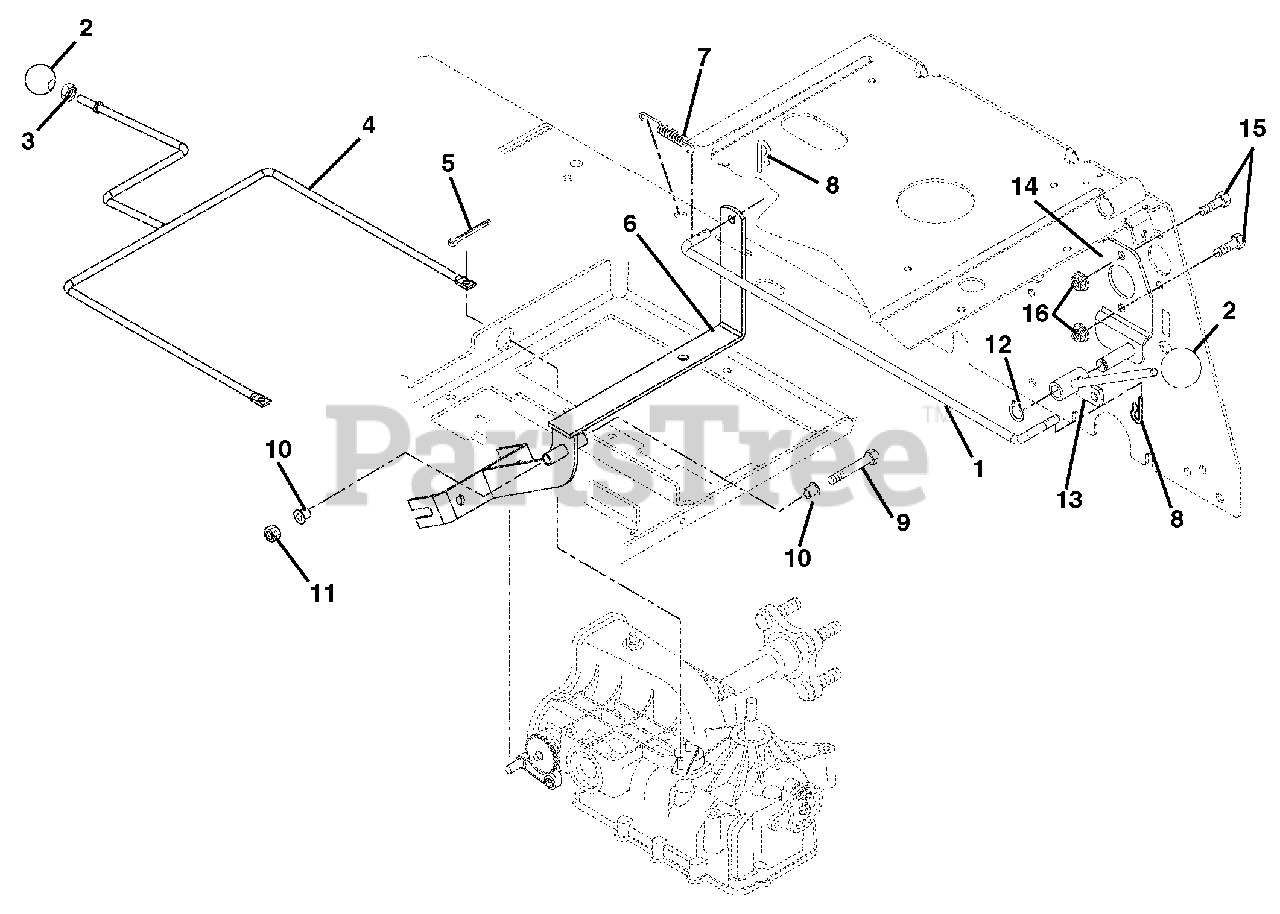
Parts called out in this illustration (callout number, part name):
1	Rod-Brake
3	Nut-Jam .31-18
4	Dump Valve Weldment
5	Pin-Cotter .09 x .75
6	Brake Weldment
7	Spring-Tension .051 x .60 x 2.25
8	Pin-Hair Internal .08 x .18 x 1.18
9	Bolt-Hex .25-20 x 3.00
10	Bushing-Flange .257 x .38 x 1.080
11	Nut-Locking-Center .25-20
12	Ring-Retaining External .50 x .050
13	Lever-Brake
14	Pivot-Brake Lever
15	Bolt Serrated Hex Flange Washer Head .31-18 x .62 Grade 5
16	Nut-Locking-Top-Flange .31-18
